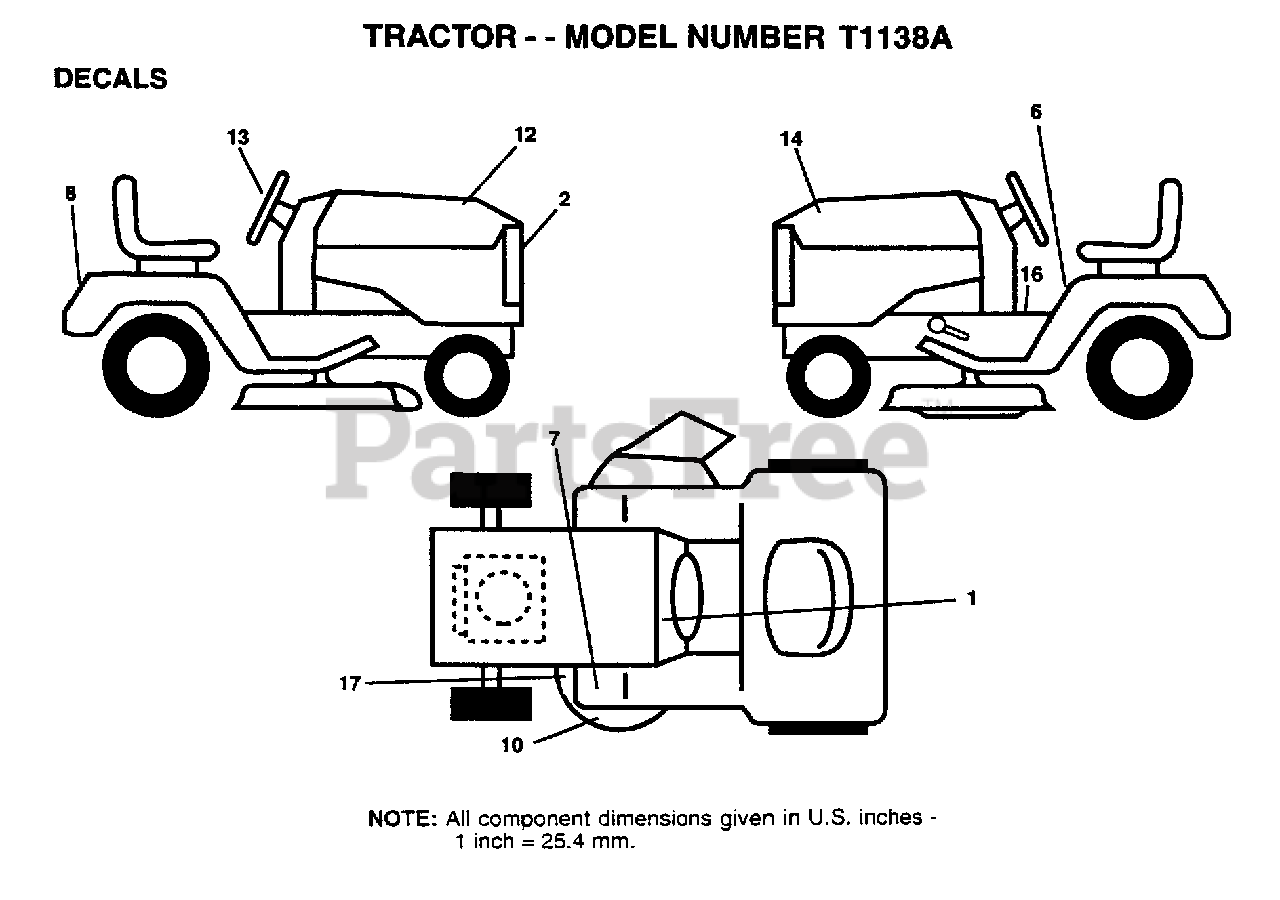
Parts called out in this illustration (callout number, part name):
1	DECAL.DASH.INST.
2	DCL.GRL.11.38.4SP
6	DECAL
8	DCL.FNDR.11.38.4S
12	DCL.HD.RH.11.38
13	"DECAL,STR WHL T"
14	DCL.HD.LH.11.38
16	DECAL BRAK PARK
17	DECAL
